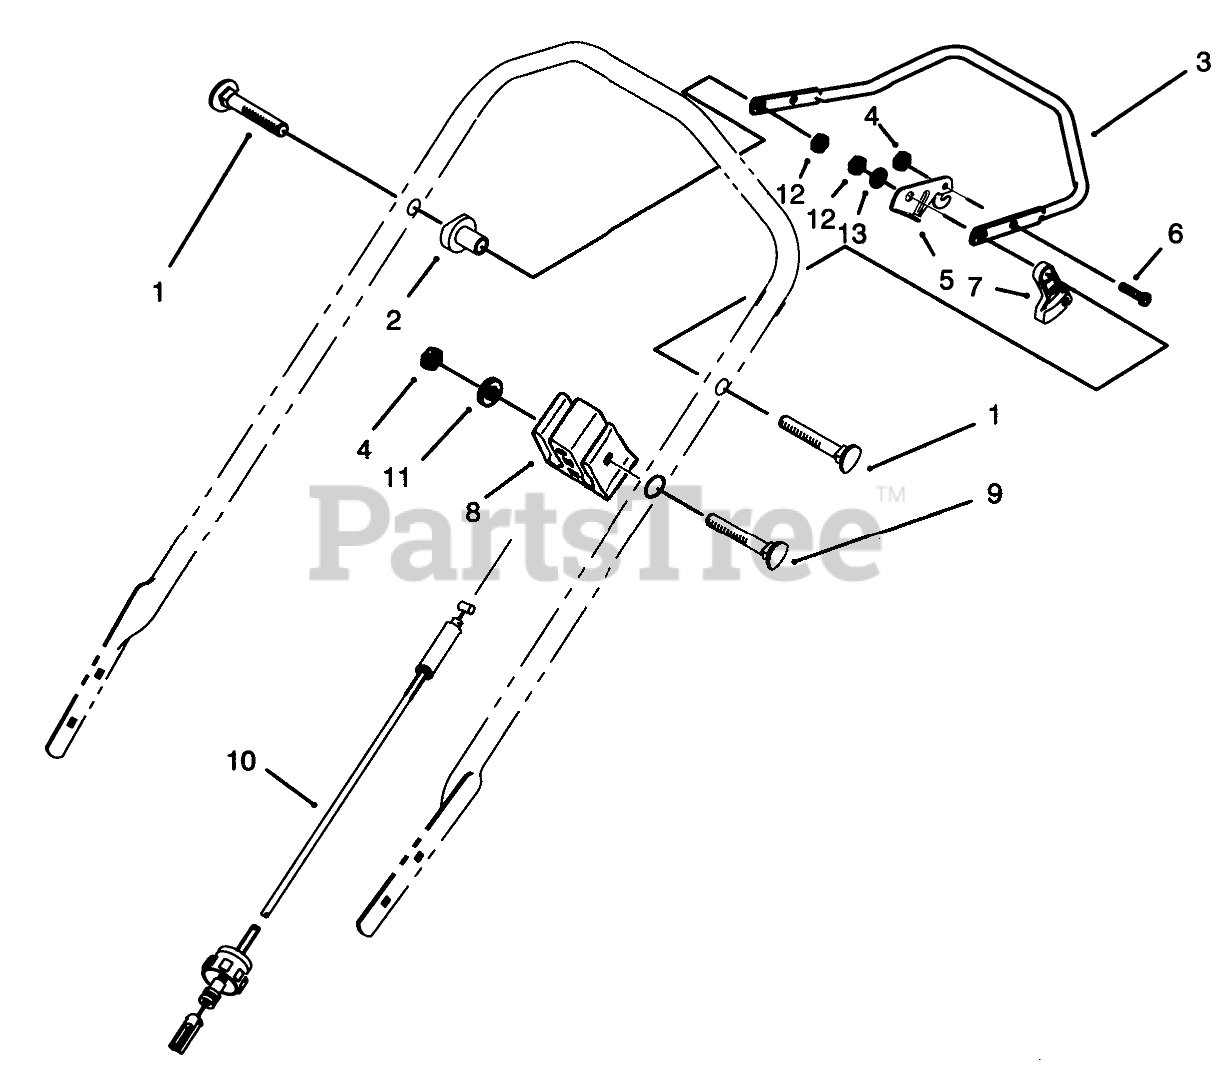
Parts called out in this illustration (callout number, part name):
1	SCREW-HANDLE
2	SPACER-SUPPORT
3	Bar-Control
4	NUT-LOCK, NI
5	CONTROL LEVER
6	SCREW-HH
7	LEVER-TRACTION
8	SUPPORT-CABLE
9	SCREW-HANDLE
10	TRACTION CABLE
11	WASHER-FLAT
12	NUT-LOCK, NI
13	WASHER-PLAIN
